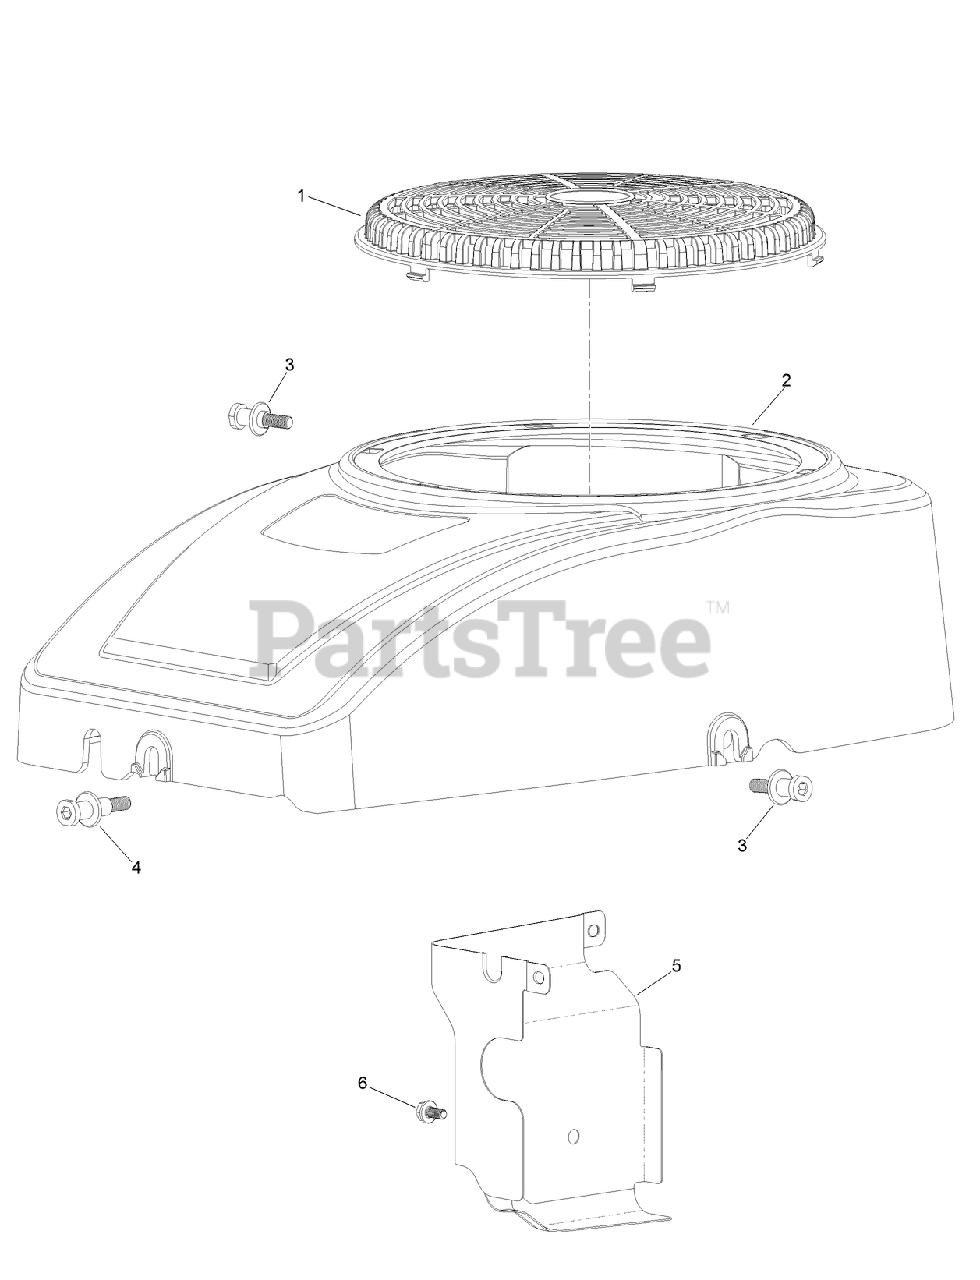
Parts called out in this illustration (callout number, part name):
1	SCREEN-STATIONARY
2	SHROUD-FAN
3	SCREW-SHOULDER, HH
4	SCREW-SHOULDER, HH
5	SHIELD
6	SCREW-HHF
